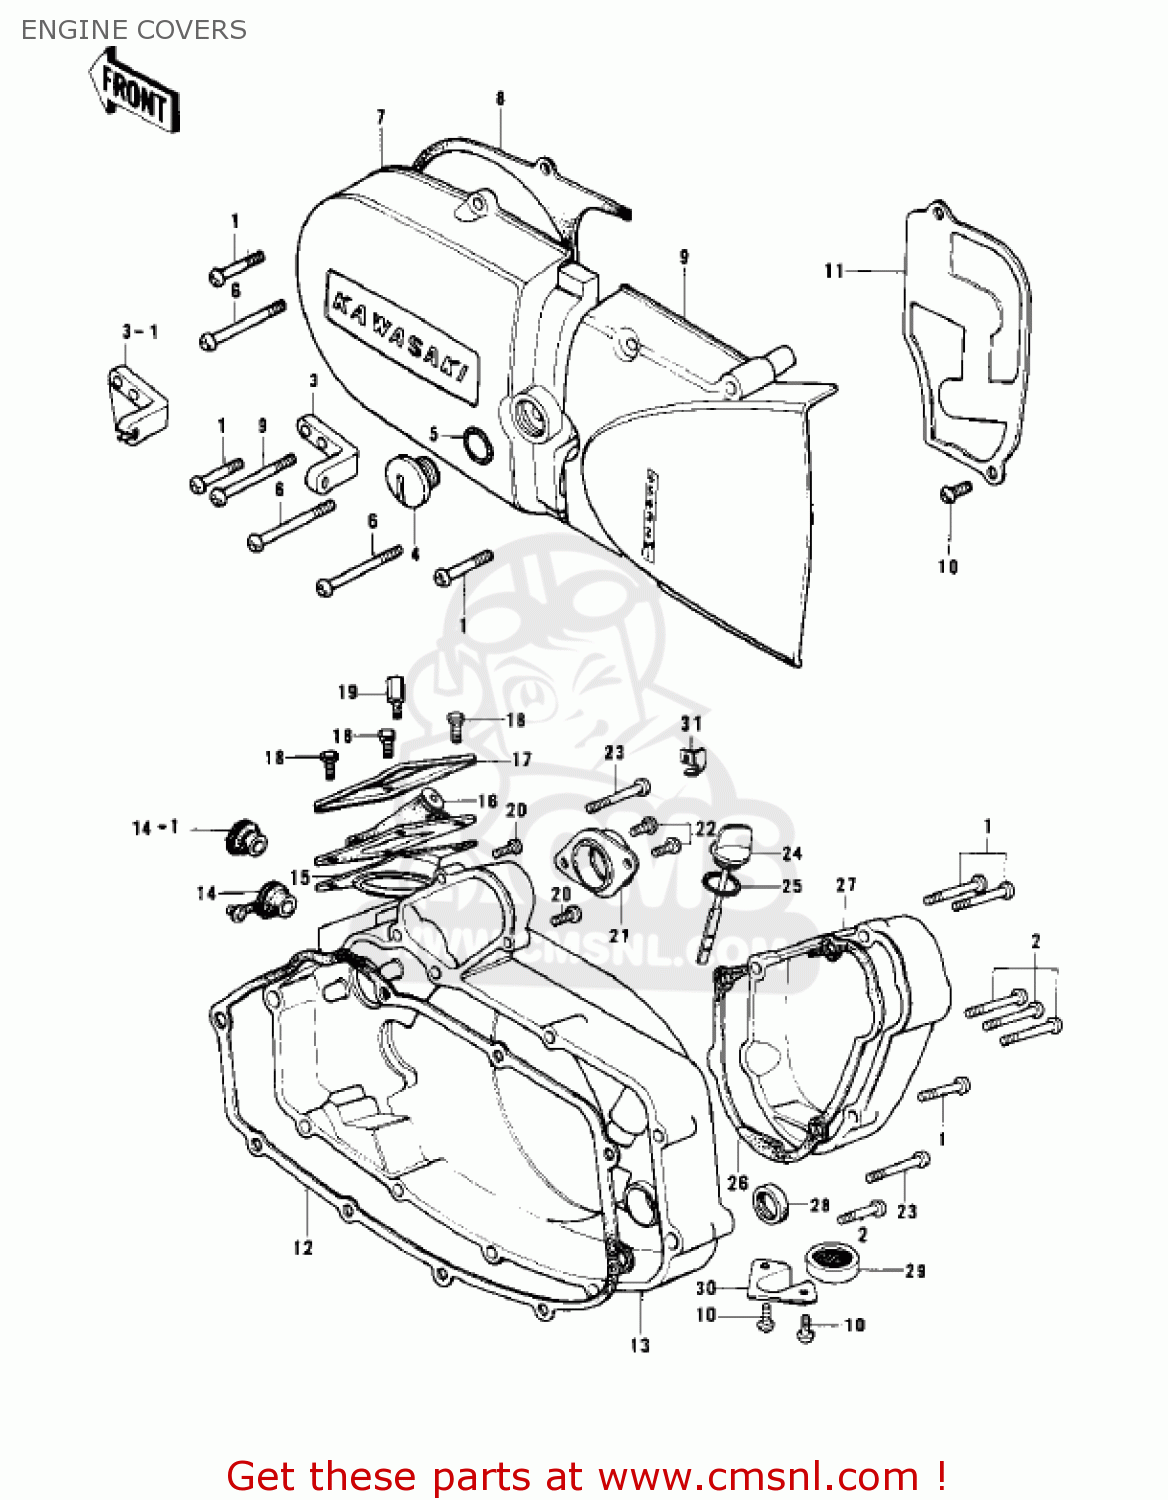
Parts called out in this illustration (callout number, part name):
1	SCREW-PAN HEAD,6X20
2	SCREW-PAN HEAD,6X30
3	HOLDER-CABLE,CLUTCH
4	PLUG,ENGINE COVER,LH,
5	O RING,16MM
6	SCREW-PAN HEAD,6X35
7	COVER,L.H ENG,BARREL
8	GASKET,L.H ENG COVER (MCA)
9	COVER, CHAIN CASE
10	SCREW-PAN HEAD,6X12
11	COVER,OIL PUMP
12	GASKET,R.H ENG COVER (MCA)
13	COVER,R.H ENGINE
14	CAP,RUBBER
15	BOOT,CARBURETOR
16	CAP,CARBURETOR
17	HOLDER,CARBURETOR BOO
18	BOLT-UPSET
19	BOLT,CARBURETOR CAP
21	HOLDER-CARBURETOR
22	SCREW-PAN HEAD,6X12
23	SCREW-PAN HEAD,6X45
24	PLUG,OIL FILLER
25	O RING,20MM
26	GASKET,CARB COVER (MCA)
27	COVER,CARB,BARREL
28	OIL SEAL SB16244
29	PLUG,25X12
30	COVER,FUEL DRAIN
31	GUIDE, CABLE
